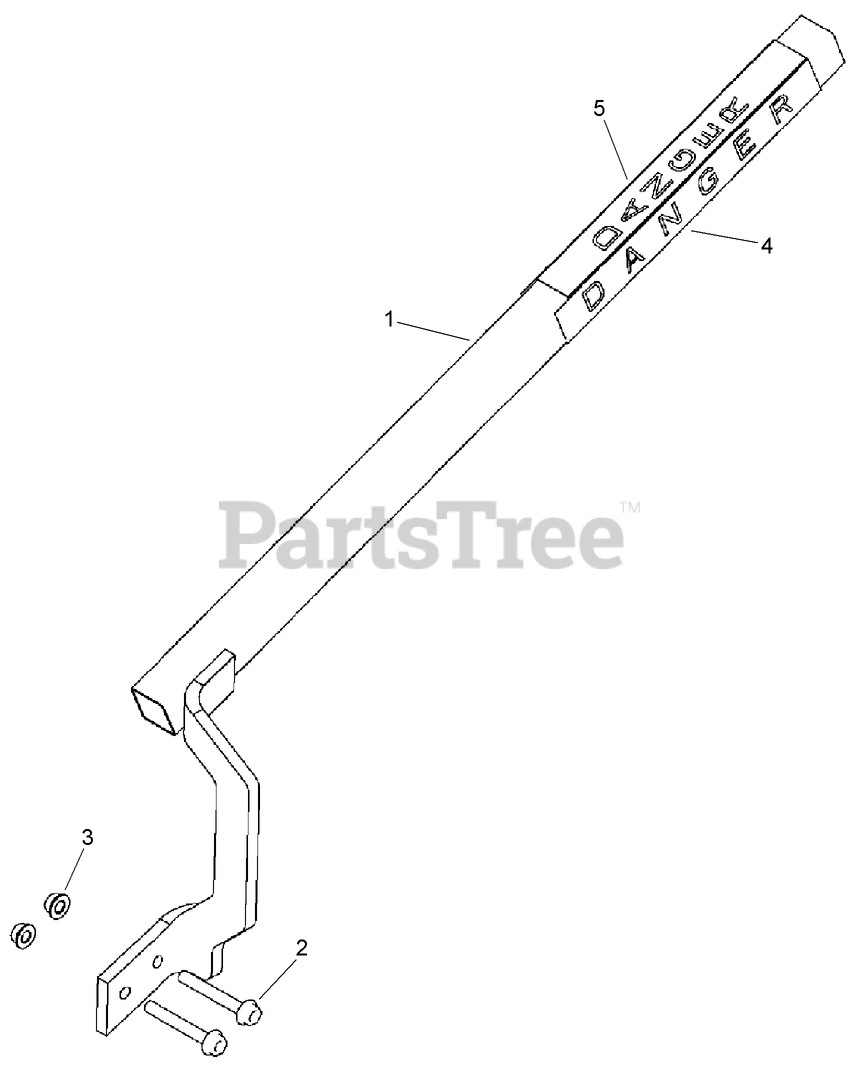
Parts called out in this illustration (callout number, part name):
1	RESTRAINT BAR - 24in Boom
1	RESTRAINT BAR - 36in Boom
1	RESTRAINT BAR - 48in Boom
3	NUT, METRIC FLANGE PREVAILING - M16 Zinc
4	DECAL-Danger, Entanglement Hazard
5	DECAL-Danger
